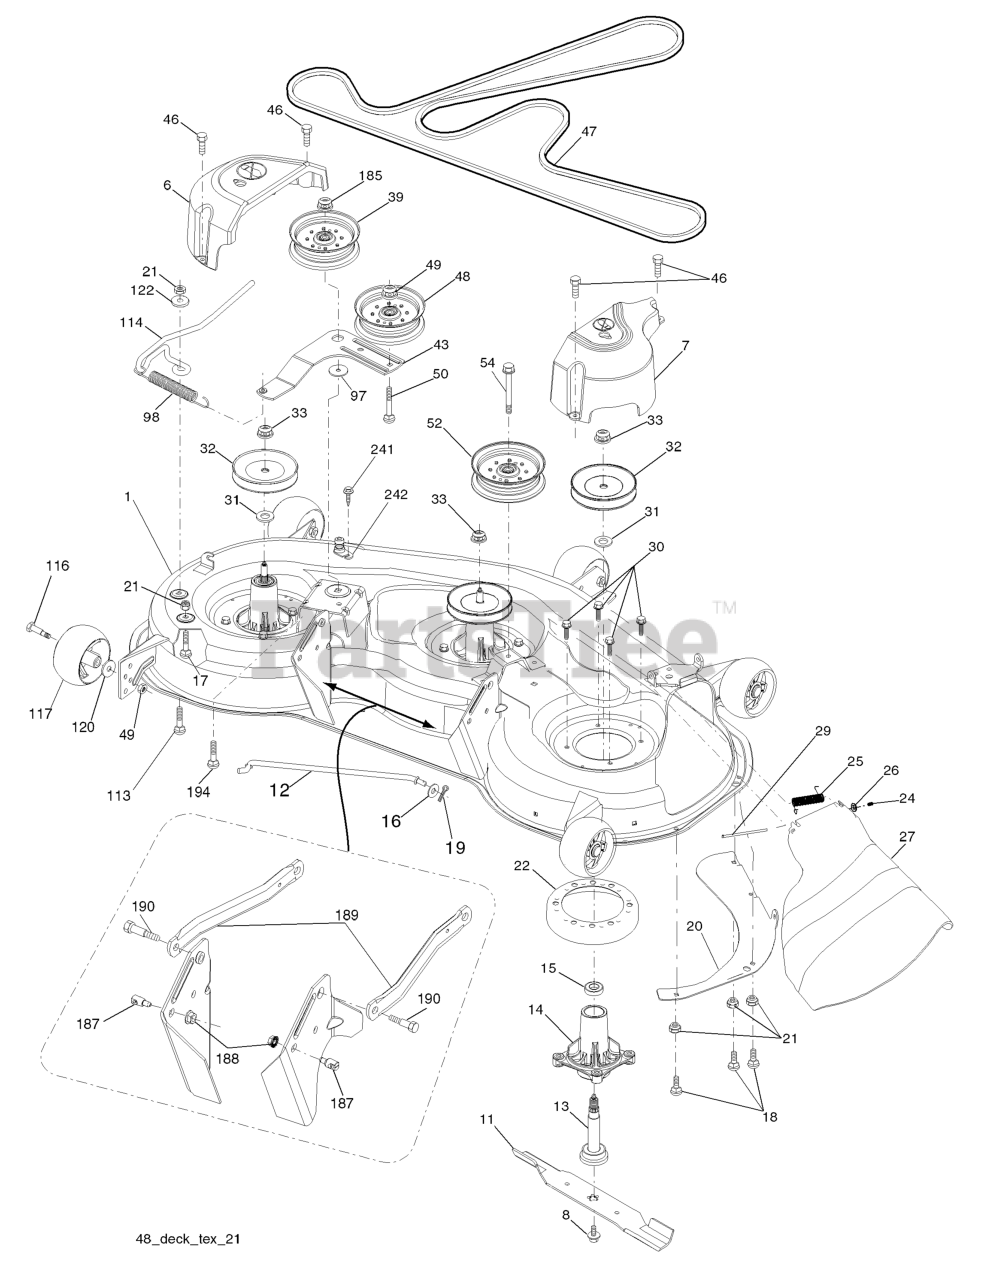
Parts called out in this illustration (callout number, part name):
1	DECK.WLDMT.W/TUBES.48"MS422
6	COVER.MANDREL.LH.48"(2 2)
7	COVER.MANDREL.RH.48"
8	BOLT 7/16 ASM BLADE
11	48" HI-LIFT BLADE
11	BLADE.MULCH.48"
12	ROD.ANTI.SWAY.48/54"TE
13	SHAFT ASM MANDREL
14	RP.HOUSING.MANDREL.4PT.
16	WASHER
17	BOLT.CARR.5/16-18X5/8.SHORT
18	BOLT
19	PIN.COTTER.5/16.BOW TI
20	BAFFLE, VORTEX MWR
21	LOCKNUT
22	STRIPPER.MANDREL.ROUND.BLACK
24	CAP-SLEEVE LT
25	SPRING, TORSION
26	NUT PUSH M
27	DEFLECTOR SUBS TO 532 180655
29	ROD.HINGE
30	SCREW, WASHER HEAD
31	WASHER.SPACER.MANDREL
32	PULLEY MANDREL
33	NUT.FLANGE.LOCK.TOP
39	RB PULLEY.IDLER.4.50/HUB SPEC
43	ARM.IDLER
46	SCREW.1/4-20X5/8
47	BELT.DRIVE.DECK
48	PULLEY.IDLER.48"PRIMARY
49	NUT LOCK FLG 3/8-16 UNC
50	BOLT.3/8-16X1.50
52	PULLEY.IDLER.2006
54	SCREW TT 3/8-16X2-1/4 UNC
98	SPRING, DECK DRIVE
113	BOLT CRT
114	ROD.TENSION.RELIEF.TEX (2 2)
116	BOLT.SHOULDER.3/8-16X3-5/8.
117	RP WHEEL. GUAGE RALLY
120	WASHER
122	BUSHING.RELIEF.TENSION
185	NUT.LOCK.FLANGE.7/16
187	STUD.FASTNER.W/ANTI-ROTATE
188	NUT LOCK HEX FLANGE 5/16-18
189	ARM.SUSPENSION.MOWER
190	BOLT.SHOULDER
194	BOLT.CARR.SQNK.7/16
241	SCREW.TT.#10-32X.5.3/8.FLANGE
242	PORT.WASHOUT
242	RP.MANDREL ASM. SERVICE
242	COUPLING.QUICK CONNECT
242	DECK.ASM SVC.48".5GWB.ORANGE
